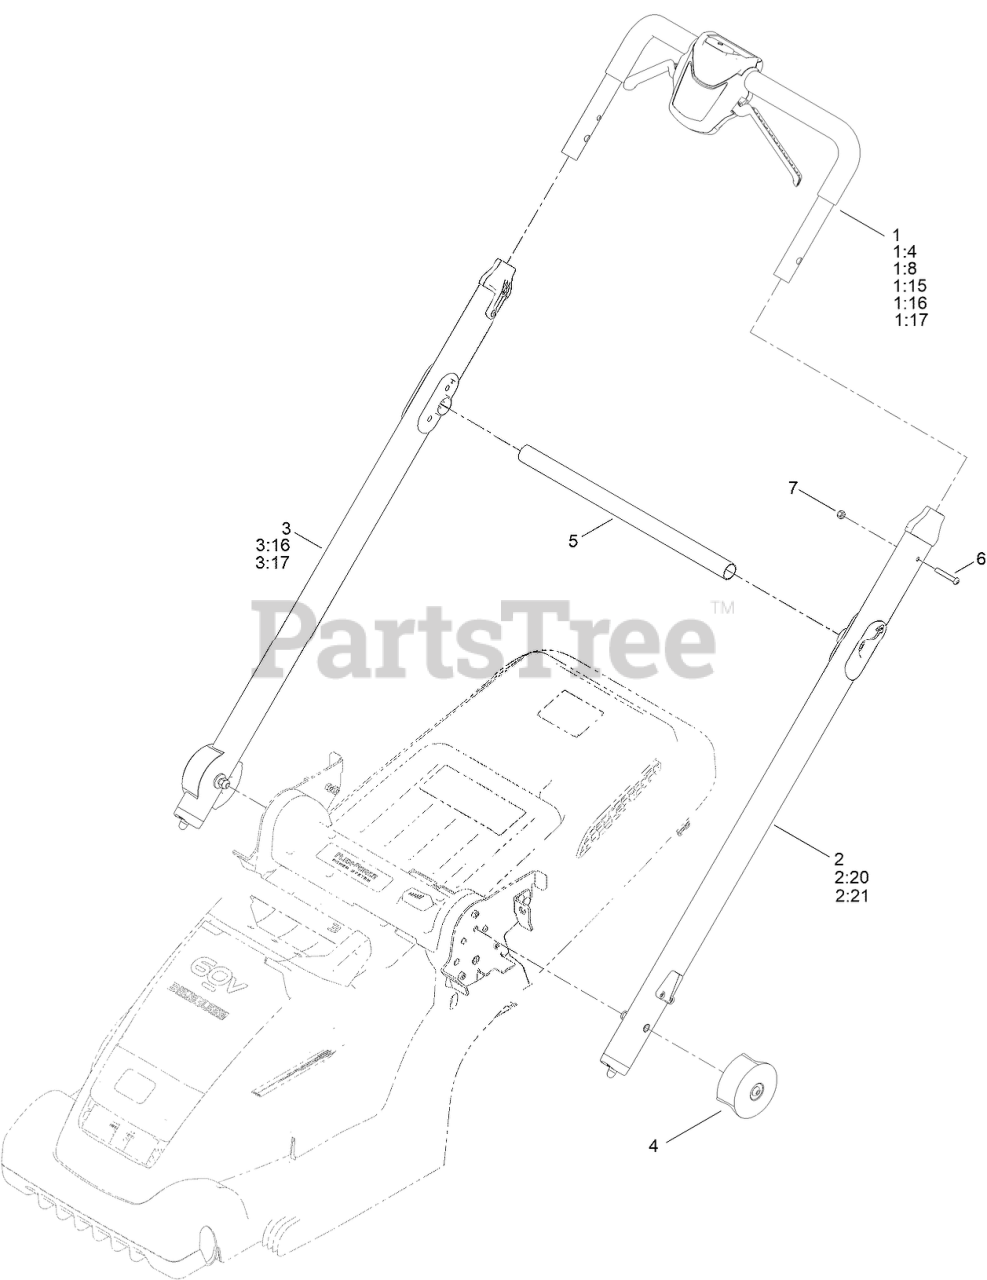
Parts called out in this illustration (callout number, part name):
1	CONTROL LEVER ASM, PUSH
1:4	TOP BUTTON KIT
1:8	UPPER LEVER KIT (43)
1:15	DECAL - VOLTA HANDLE
1:16	DECAL - BOOST KEY MAT
1:17	WIRING LOOM, PUSH
2	HANDLEBAR ASM, LH
2:20	HANDLEBAR BRACE - INNER
2:21	HANDLEBAR BRACE, OUTER
3	HANDLEBAR ASM, RH
3:16	HANDLEBAR BRACE - INNER
3:17	HANDLEBAR BRACE, OUTER
4	HANDLEBAR END CAP
5	BRACE, HANDLEBAR RELEASE
6	BOLT, M6X40
7	NUT, M6, NYLOC
